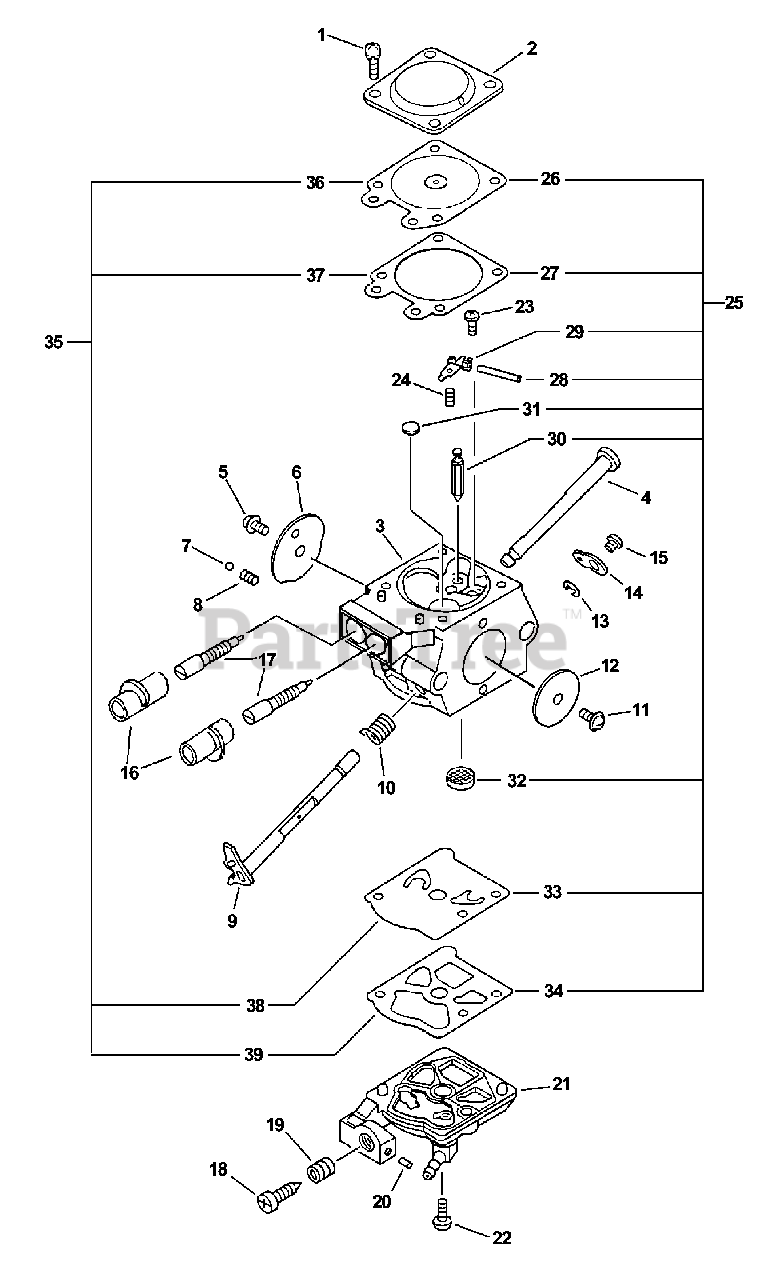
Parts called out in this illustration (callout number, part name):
1	SCREW
2	COVER, METERING DIAPHRAGM
3	BODY, CARBURETOR
4	SHAFT, CHOKE
5	SCREW, VALVE
6	VALVE, CHOKE
7	BALL, CHOKE FRICTION
9	SHAFT, THROTTLE
10	SPRING, THROTTLE RETURN
11	SCREW, VALVE
12	VALVE, THROTTLE
14	LEVER, THROTTLE
15	SCREW, VALVE
16	CAP, LIMITER
17	NEEDLE, MIXTURE
18	SCREW, IDLE ADJUST
19	SPRING, IDLE ADJUST
20	PLUG, FRICTION
21	COVER, FUEL PUMP
23	SCREW, METERING LEVER PIN
24	SPRING, METERING LEVER
25	REPAIR KIT, CARBURETOR
26	DIAPHRAGM, METERING
27	GASKET, METERING
28	PIN, METERING LEVER
29	LEVER, METERING
30	VALVE, INLET NEEDLE
31	PLUG, WELCH
32	STRAINER
33	DIAPHRAGM, PUMP
34	GASKET, PUMP
35	GASKET / DIAPHRAGM KIT
36	DIAPHRAGM, METERING
37	GASKET, METERING
38	DIAPHRAGM, PUMP
39	GASKET, PUMP
